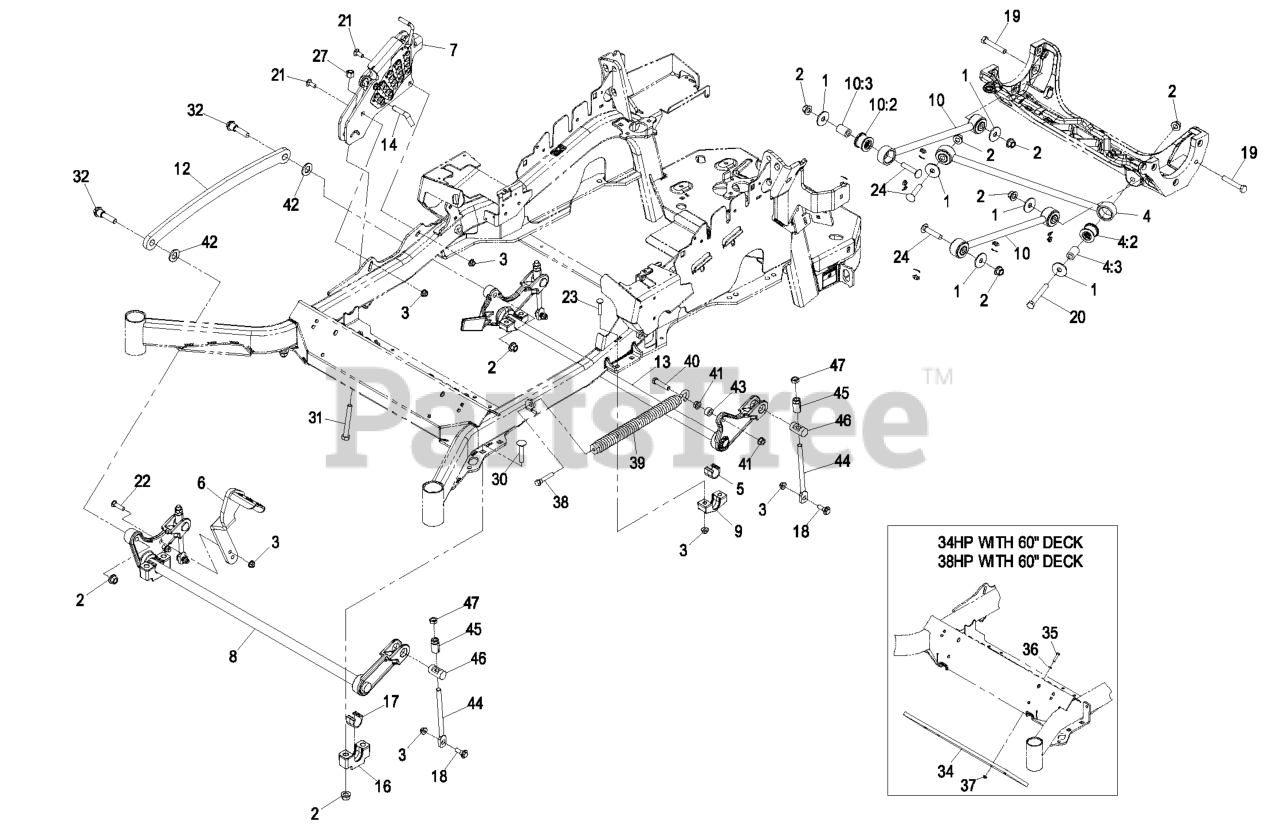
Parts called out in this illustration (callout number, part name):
1	WASHER-THRUST
2	Nut-Lock 1/2-13
3	NUT-HF, NI
4	PANHARD ROD ASM
4:2	BUSHING-SUSPENSION, RUBBER
5	BEARING-CROSS SHAFT, REAR
6	LEVER-FOOT
7	HOC ASM
10	DECK STRUT ASM
10:2	BUSHING-SUSPENSION, RUBBER
12	LINK-LIFT, DECK
13	LIFT-DECK, REAR
14	PIN-HOC
16	SUPPORT-CROSS SHAFT, BEARING
17	BEARING-CROSS SHAFT, FRON
18	SCREW-SHOULDER, HHF
19	SCREW-HH
20	SCREW-HH
21	BOLT-CARR
22	SCREW-CARR
23	SCREW-CARR
24	SCREW-CARR
27	NUT-LOCK, NI
30	Bolt-Carriage 1/2-13 X 2 1/2 Spl Neck
31	BOLT-TAP
32	SCREW-HHF, SHOULDER
34	WEIGHT,TOE BOARD
35	SCREW-HH
36	WASHER-FLAT
38	BOLT-SHOULDER
39	SPRING-EXTENSION
40	SCREW-HH
42	WASHER-FLAT
44	LINK-ADJUSTER, DECK LIFT
45	ADJUSTER-LIFT, DECK
46	TRUNNION
47	NUT-JAM
